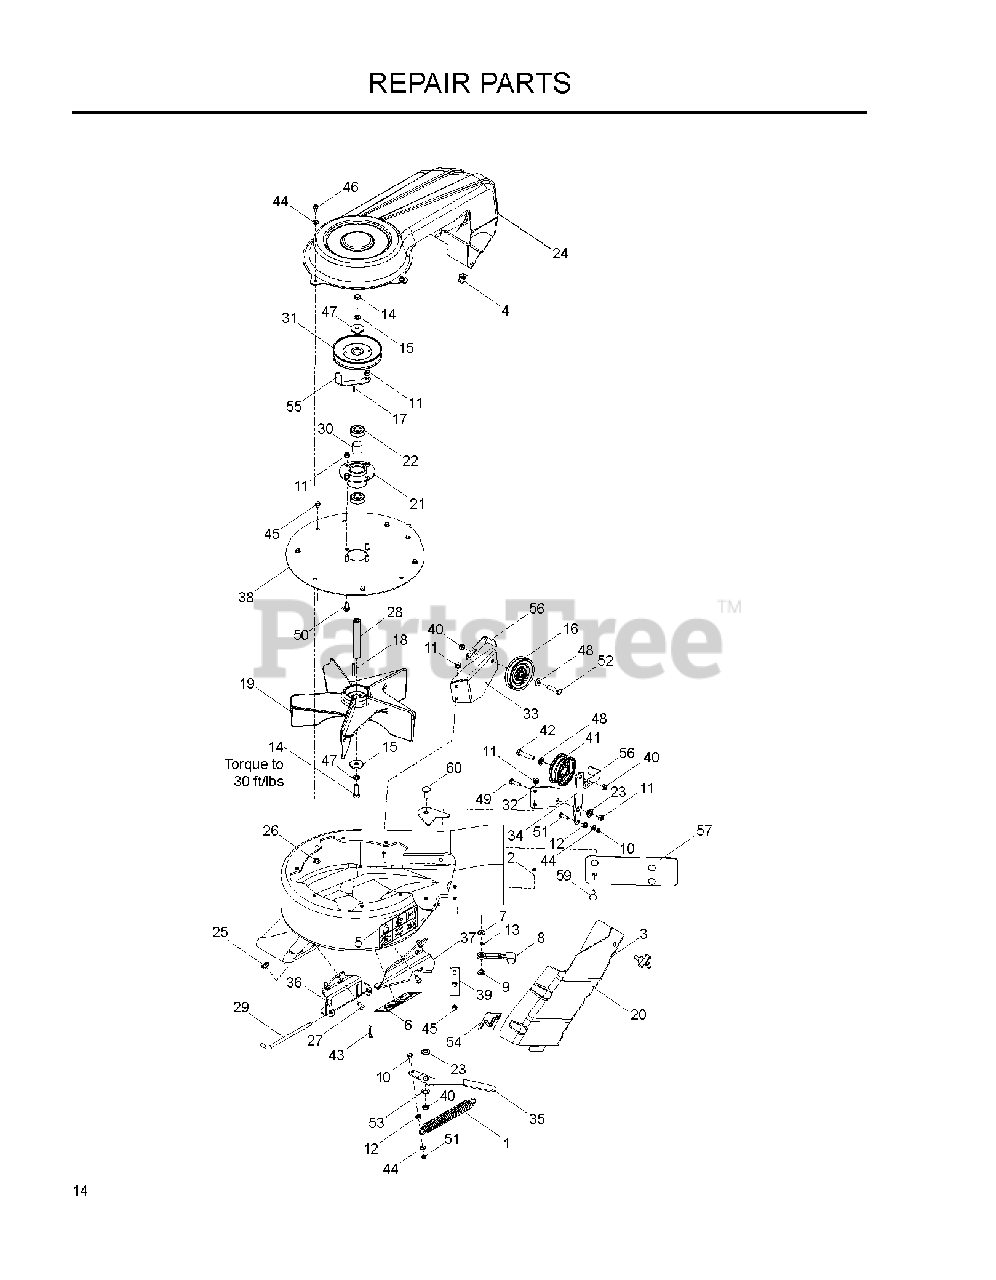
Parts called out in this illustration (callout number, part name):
2	SCREW #10-24 X 5/8
3	KNOB W/STUD
4	U-CLIP 5/16-18 NUT RETAINER
5	DECAL, EURO WARNING
6	EURO DECAL, IMPELLER
8	HOOD LATCH
9	NUT 10-24 WELD PLATED
10	JAM NUT 1/4C
11	NUT 5/16 NYLOC
12	NUT 1/4-20 HEX FLG LK ZD
13	WASHER - 3/16 LOCK ZD
14	BOLT, HEX 3/8-24 X 1.25 GR 8
15	WASHER, HARDENED
16	V-IDLER
17	KEY, 3/16 X 1/2
18	KEY-SQ. 3/16 X 1 1/2
19	IMPELLER.COLLECTION.BLOWER.BLA
20	COVER, BELT
21	HUB, BEARING
22	BEARING
23	BUSHING
24	COVER, BELT
25	NUT 5/16-18 TEE
26	NUT 1/4-20 TEE
27	HCS 5/16-18 X 1/2 GR 5 ZD
28	SHAFT, IMPELLER
32	MOUNT, IDLER, UPPER
33	MOUNT, IDLER, LOWER
34	ARM, IDLER
35	ARM, TENSION
36	BRKT, MT, FRONT
37	BRKT, MT, REAR
38	PLATE, OUTER
40	NUT HEX 3/8-16 NYLON, THIN
41	IDLER PULLEY
42	BOLT, HCS 3/8-16X1-3/4
43	HAIRPIN #2
44	WASHER 1/4 SAE
45	HWST 1/4C X 3/8
46	BOLT 1/4-20 X 1/2 HWST
47	SLW 3/8 STD
48	WASHER 3/8 SAE FLAT
49	HCS 5/16C X 1
50	BOLT 5/16C X 3/4" CARRIAGE
51	HCS 1/4-20X7/8 GR5
52	HCS 3/8C X 1 1/2
53	WASHER 5/16 FLAT
54	DECAL, BELT ROUTING
55	KEEPER, BELT, OUTER
56	KEEPER, BELT, REAR
57	PLATE.BACKING.BLACK
58	PLATE, BACKING
59	RHSNB 5/16C X 1
60	RHSNB 3/8C X 1
61	BLOWER.HOUSING.W/DECALS.COLLEC
